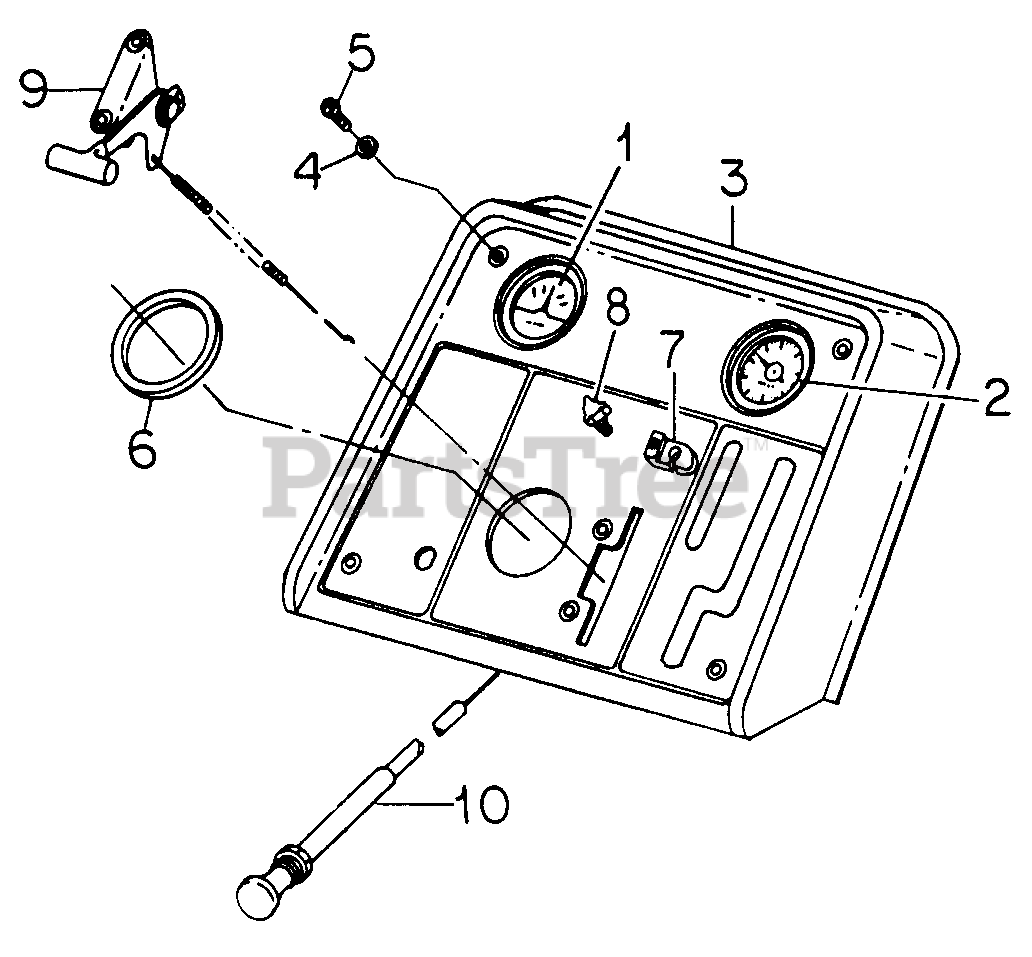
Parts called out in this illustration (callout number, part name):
1	Indicator, Charge
2	Timer, Maintenance Minder - Not Serviced Separately
3	Panel, Instrument
4	Washer, Flat
5	Screw, Tapping
6	Grommet, Instrument Panel
7	Stop, Handle Detent
9	Control, Throttle
10	Cable, Choke
